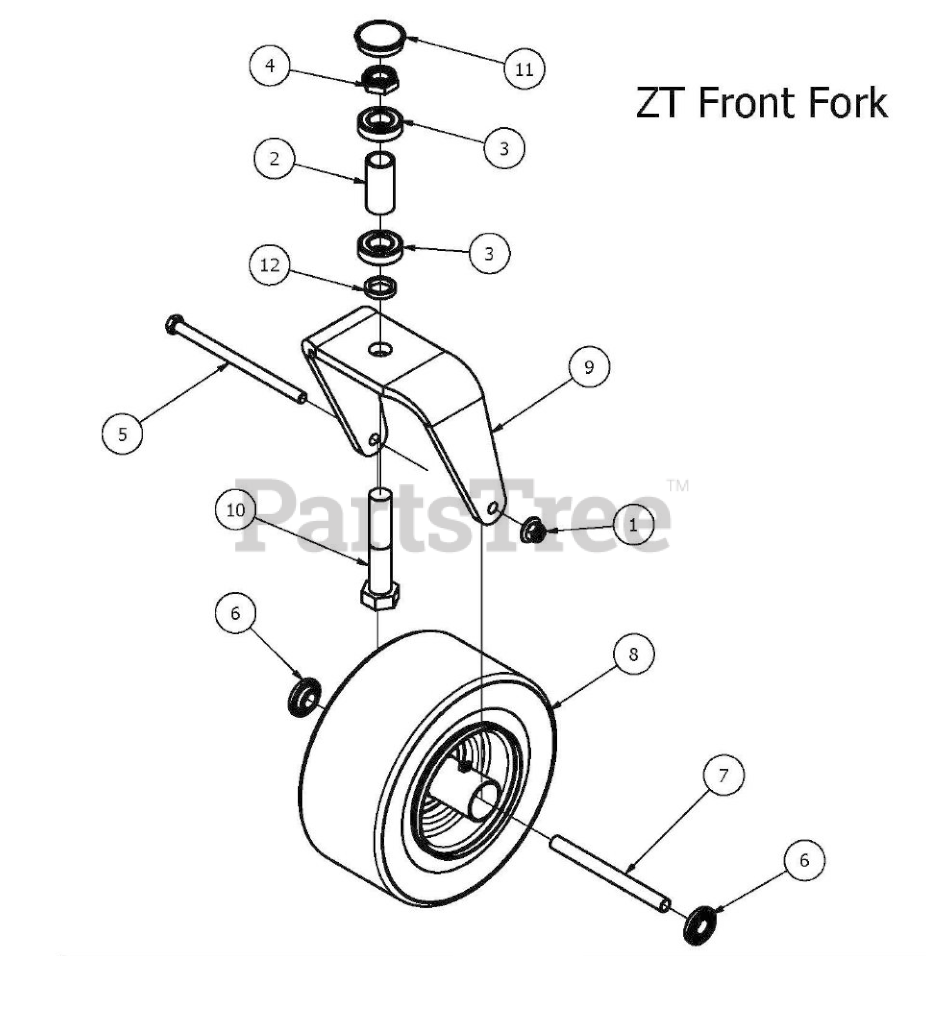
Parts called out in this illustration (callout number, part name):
1	1/2-13 Nylon Insert Flange Nut
2	2016 Front Bearing Spacer
3	Caster Bearing 2016 - 1641 Bearing
4	1" Fine Thread 1/2 Nylock Nut
5	1/2" x 8 1/2 GR 5 Hex Bolt
6	1 3/8" Wheel Bearing
7	Front Wheel Spanner
8	Tire and Wheel Assembly
9	2017 ZT Front Fork
10	1-14 x 5 Hex Bolt Grade 8 Zinc Yellow
11	2017 Bearing Cover
12	1" x .25" Spacer
